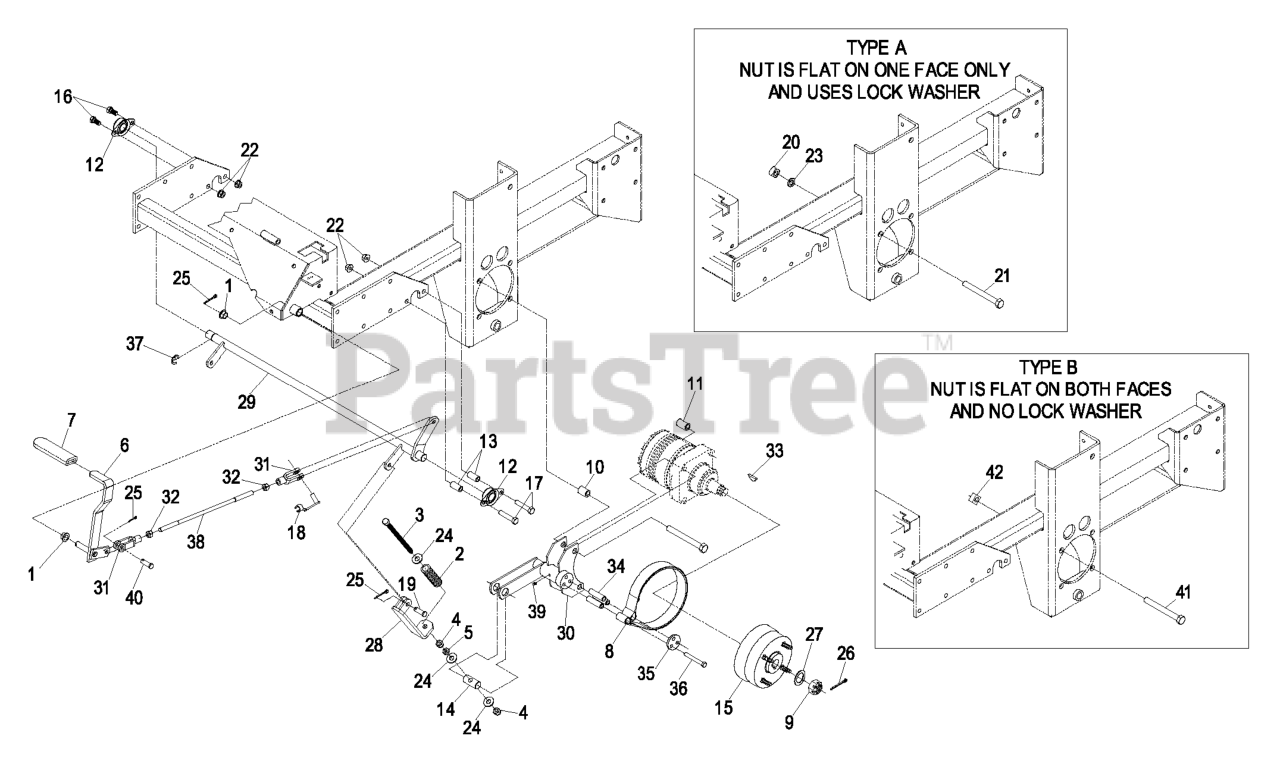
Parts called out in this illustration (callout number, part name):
1	BEARING-CONTROL
2	SPRING-COMPRESSION
3	BOLT-TAP, HH
4	NUT-LOCK, NI
5	NUT-JAM
6	BRAKE LEVER AND GRIP ASM
7	GRIP-LEVER
8	BAND,BRAKE
10	SPACER-WHEEL, SHORT
11	SPACER-WHEEL, LONG
12	BEARING-FLANGE, SIDE
13	SPACER-RETAINER, BRAKE
14	PIN-TRUNION
15	WHEEL HUB ASM
16	SCREW-HH
17	SCREW-HH
18	PIN-SPRING, CLEVIS
19	PIN-CLEVIS
21	SCREW-HH
22	NUT-HHF, WHIZ
23	WASHER-LOCK
24	WASHER-FLAT
25	PIN-COTTER
26	PIN-COTTER
27	WASHER-SPACER
28	LINKAGE-BRAKE, LOWER
29	SHAFT-BRAKE
30	BRAKE-NARROW
31	YOKE-LINKAGE, BRAKE
32	NUT-HEX
33	KEY-WOODRUFF
35	RETAINER-BAND, BRAKE
36	SCREW-HH
38	ROD-BRAKE
39	FITTING-GREASE
40	PIN-CLEVIS
41	SCREW-HH
42	NUT-SQUARE, SPECIAL
